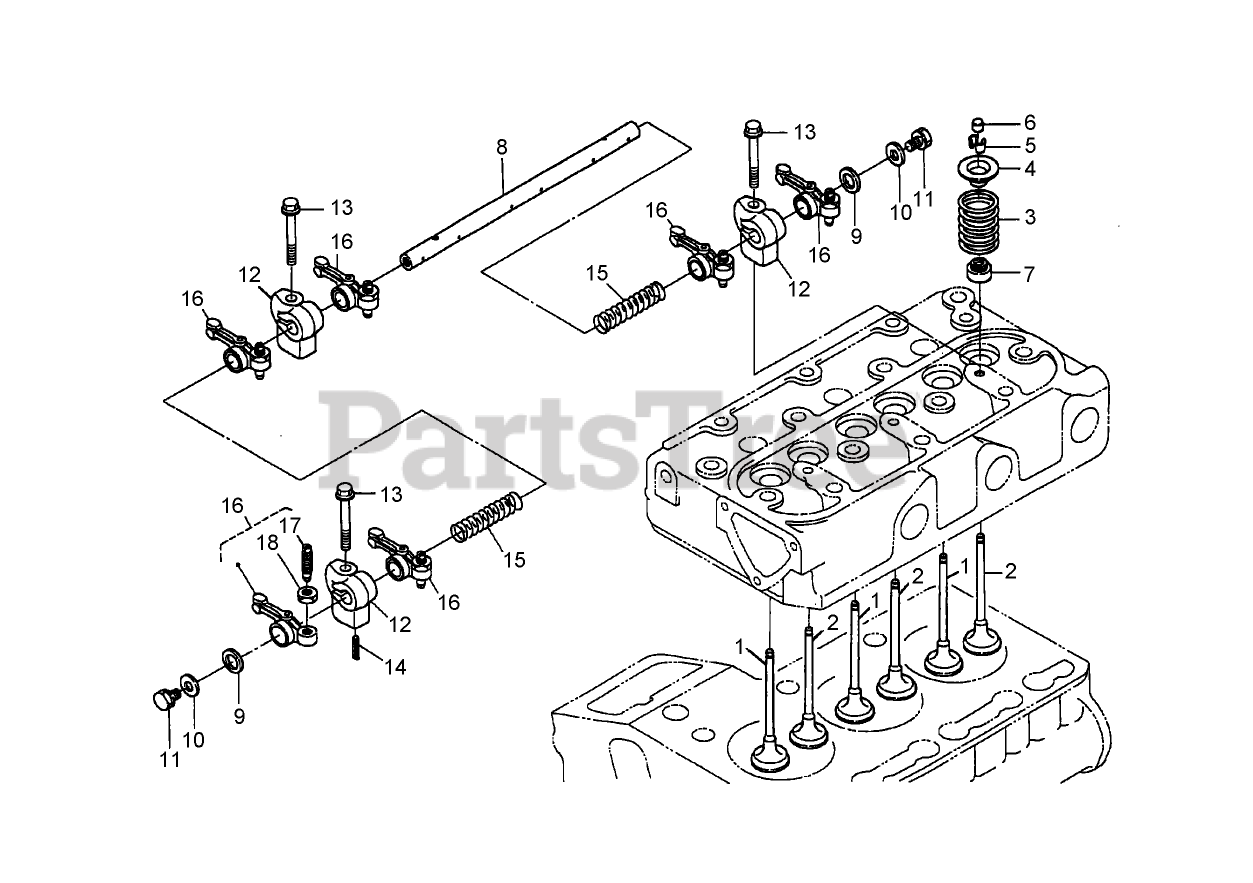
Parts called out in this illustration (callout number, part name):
1	VALVE-INLET
2	VALVE-EXHAUST
3	SPRING-VALVE
4	RETAINER-SPRING, VALVE
5	COLLET-SPRING, VALVE
6	CAP-VALVE
7	SEAL-STEM, VALVE
8	SHAFT-ARM, ROCKER
9	WASHER
10	WASHER-PLAIN
12	BRACKET-ARM, ROCKER
13	BOLT-FLANGE
14	PIN-SPRING
15	SPRING
16	ROCKER ARM ASM
17	SCREW-ADJUSTING
